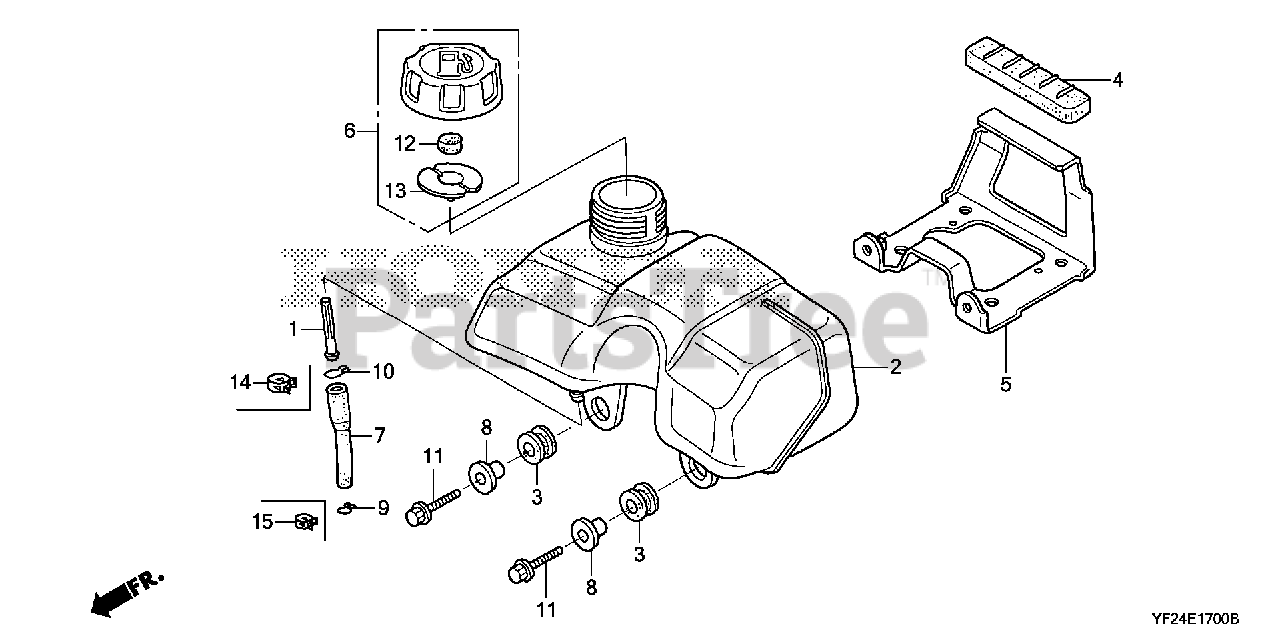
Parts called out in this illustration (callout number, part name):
1	FILTER, FUEL
2	TANK, FUEL
2	TANK, FUEL (FOR U.S.A.)
3	RUBBER A, TANK MOUNTING
4	RUBBER B, TANK MOUNTING
5	STAY, FUEL TANK
6	CAP ASSY., FUEL TANK
7	TUBE A, FUEL
7	TUBE A, FUEL (FKM)
8	COLLAR, CANISTER MOUNTING
9	CLIP, TUBE (B8)
10	CLIP, TUBE (B10)
11	BOLT, FLANGE (6X20)
12	SPONGE, FUEL CAP BREATHER
13	GASKET, FUEL CAP
14	CLAMP, TUBE (D10.5)
15	CLAMP, TUBE (D8)
